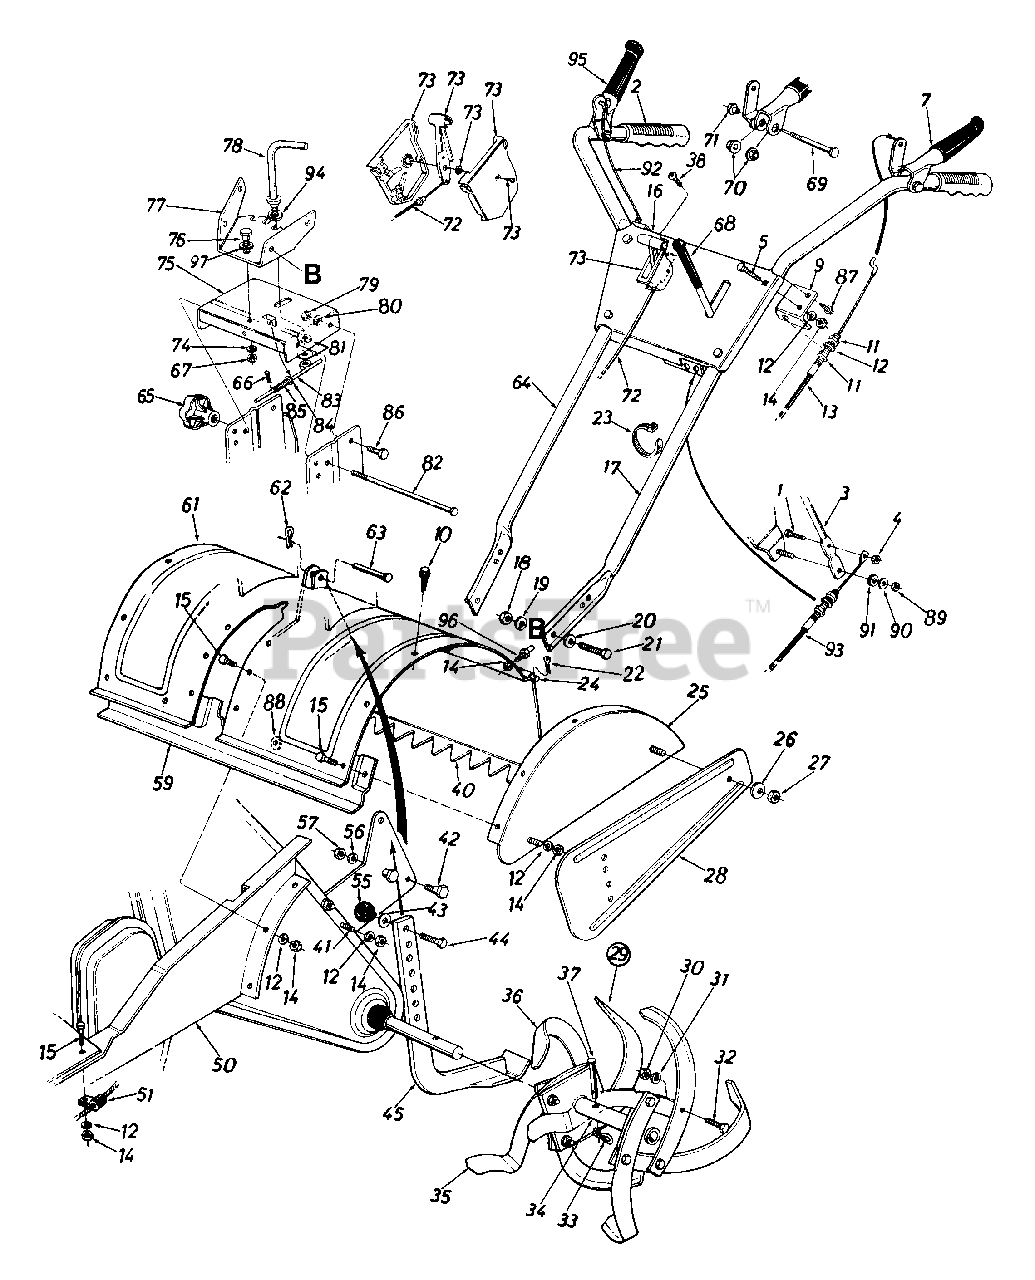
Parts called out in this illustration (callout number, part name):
1	Hex Bolt 1/4-28 x .75" Lg.
2	Grip
3	Clutch Lever
4	Hex Cent. L-Nut 1/4-28 Thd.
5	Carr. Bolt 5/16-18 x 1.75"
7	Clutch Grip Ass'y. - L.H.
9	Clutch Cable Bracket
10	Hex Wash. S-Tap Scr. 5/16-18 x .62" Lg.
11	Hex Nut 5/16-24 Thd.
12	L-Wash. 5/16" I.D.
13	Clutch Control Cable (Tines)
14	Hex Nut 5/16-18 Thd.
15	Hex Bolt 5/16-18 x .75" Lg.
19	L-Wash. 3/8" I.D.
20	Bell-Wash. 3/8" I.D.
21	Hex Bolt 3/8-16 x 1" Lg.
22	Cotter Pin 3/32" Dia. x 3/4"
23	Cable Tie
24	Tiller Flap Rod
27	Hex Nut 5/16-18 Thd.
31	L-Wash. 3/8" I.D.
32	Hex Bolt 3/8-24 x 1.25" Lg.
33	Hairpin Cotter
38	Truss Mach. AB-Tap Scr. #10 x .5" Lg.
41	Hex Bolt 5/16-18 x 1.0" Lg.
42	Shld. Bolt 1/2" Dia. x .43"
43	Fl-Wash. 3/8" I.D. x 5/8" O.D.
44	Hex Bolt 3/8-16 x 3/4" Lg.
55	Ball Knob 1 1/4" Dia.
56	L-Wash. 3/8" I.D.
57	Hex Nut 3/8-16 Thd.
63	Clevis Pin 3/8" Dia.
66	Cotter Pin 1/16" Dia. x .75"
67	Hex Cent. L-Nut 3/8-16 Thd.
69	Shoulder Bolt .375" Dia. x 1.37" Lg.
70	Hex Flange Plastic Bearing
71	Shoulder Nut 1/4-20 Thd.
72	Throttle Control Wire
73	Throttle Control Box Ass'y.
74	Bell-Wash. .40" I.D. x 1.13"
79	Hex Cent. L-Nut 3/8-16 Thd.
80	Bell-Wash. .40" I.D. x .88"
81	Bell-Wash. 1/2" I.D. x 1.00"
82	Lock Pin 5/16" Dia. x 8"
83	Lower Sliding Ass'y.
84	Fl-Wash. .291" I.D. x .62"
85	Compression Spring 1" Lg.
86	Shoulder Bolt 1/2" Dia. x .170" Lg.
87	Hex Wash. S-Tap Scr. 1/4-20 x .50" Lg.
88	Bell-Wash. 5/16" I.D.
89	Hex Cent. L-Nut 5/16-18 Thd.
90	Fl-Wash. .344" I.D. x .87"
91	Rubber Wash. .33 I.D. x .87"
92	Control Cable (Forward)
93	Control Cable (Reverse)
94	Fl-Wash. .62" I.D. x 1.57"
95	Clutch Grip Ass'y. - R.H.
96	Hex Bolt 5/16-18 Thd.
97	Fl-Wash. .64" I.D. x .94"
